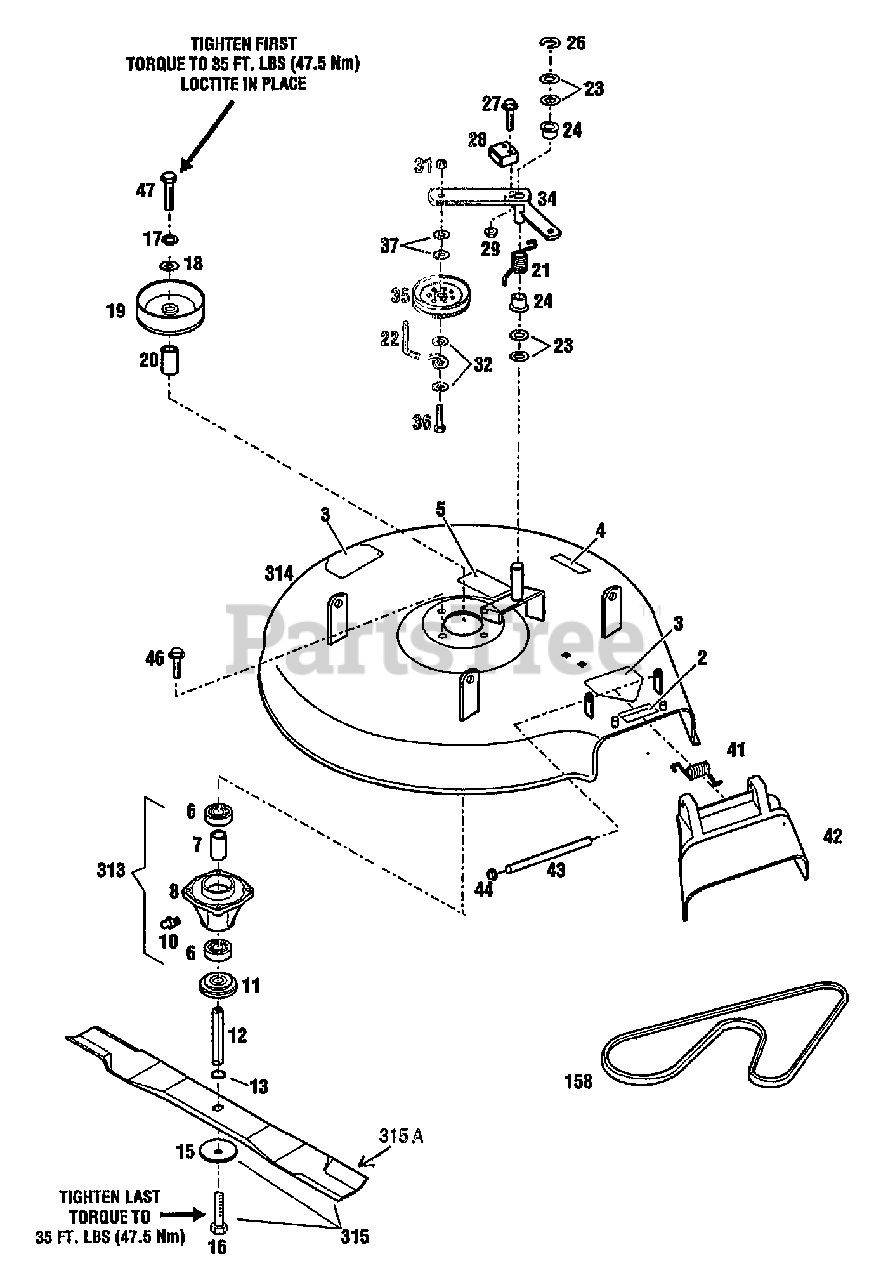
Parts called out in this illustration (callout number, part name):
2	DECAL-DANGER
3	DECAL-DANGER
4	DECAL-22" CUT {34067,30466}
4	DECAL-26" CUT {34068,34069}
5	DECAL-CAUTION PINCH POINT
6	BEARING-BALL
8	HOUSING-SPINDLE
10	FITTING-GREASE 1/4-28X2.00
11	SPACER-BLADE
12	SHAFT-SPINDLE LONG
13	RING-RETAINING EXT .694 ID
15	WASHER-LK CONICAL .49 ID
16	SCR-HH 1/2-14X1.00
17	WASHER-LK .438 ZP
18	WASHER-1.37X.453X.179 ZP
19	ASSM-SHEAVE
20	SPACER
21	SPRING-TORSION
22	GUIDE-BELT
23	WASHER-THRUST 1.1X.76X.05
24	BUSHING-NYLON
26	RING-RETAIN EXT .707 ID
27	SCR-HW M10-24X1.25 (INCL. WASHER)
28	PAD-BRAKE
29	NUT W/LKWASHER 10-24 ZP
31	NUT-H/LK 3/8-16
32	WASHER-FLAT 3/8 SAE
34	ASSM-IDLER ARM
35	IDLER 4" B-GROOVE
36	SCR-HH 3/8-16X2.0 G5 ZP
37	WASHER-FLAT 1.25X.406X.179
41	SPRING-TORSION
42	ASSM-DEFLECTOR
43	ROD-HINGE PIN
44	NUT-PUSH 3/8 ZP
46	SCR-HFLK 5/16-18X.75
47	SCR-HH 7/16-14X1.25
158	BELT-V
313	ASSM-MOWER SPINDLE (INCL. 6-8 & 10)
314	ASSM-DECK 22" {34067,34066} (INCL. 2,3, & 5)
314	ASSM-DECK 26" {34068,34069} (INCL. 2,3, & 5)
315	KIT-BLADE 22" HW MWR (INCL. 15 & 16)
315	KIT-BLADE 26" HW MWR (INCL. 15 & 16)
315A	BLADE-22" HI WHL MWR
315A	BLADE-26"
322	LOCTITE-242 (.5 ML TUBE)
